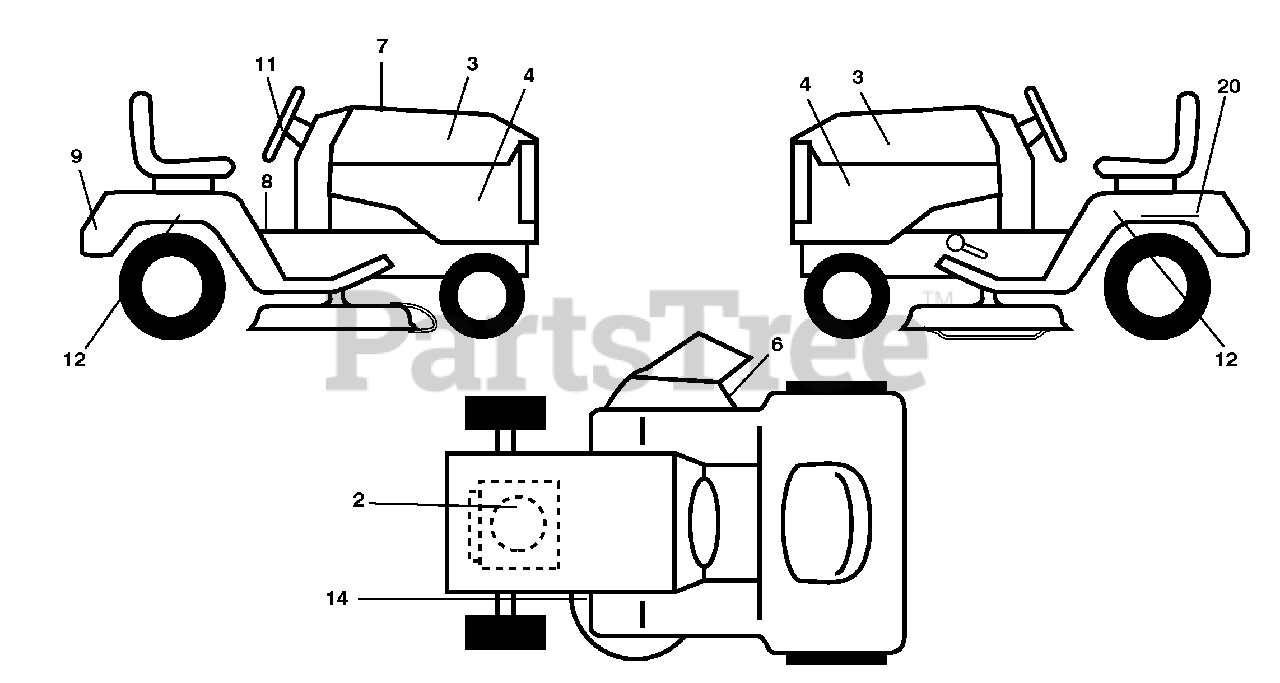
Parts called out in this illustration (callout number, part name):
2	Decal Eng. H.P.
4	Decal Side Panel Logo
6	Decal Warning, Keep Hand Away
7	Decal Replacement Parts
8	Decal Fender Warn S/F
9	Decal Fender Logo
11	Decal Ins Strg Whl
12	Decal Fend SD
14	Decal V-Belt Schematic
20	Decal Bat Dan/Psn
20	Decal Bypass
20	Pad Footrest LH
20	Pad Footrest RH
20	Manual Operator's (English/French)
20	Manual Operator's (Spanish)
20	Manual Parts (English/French)
